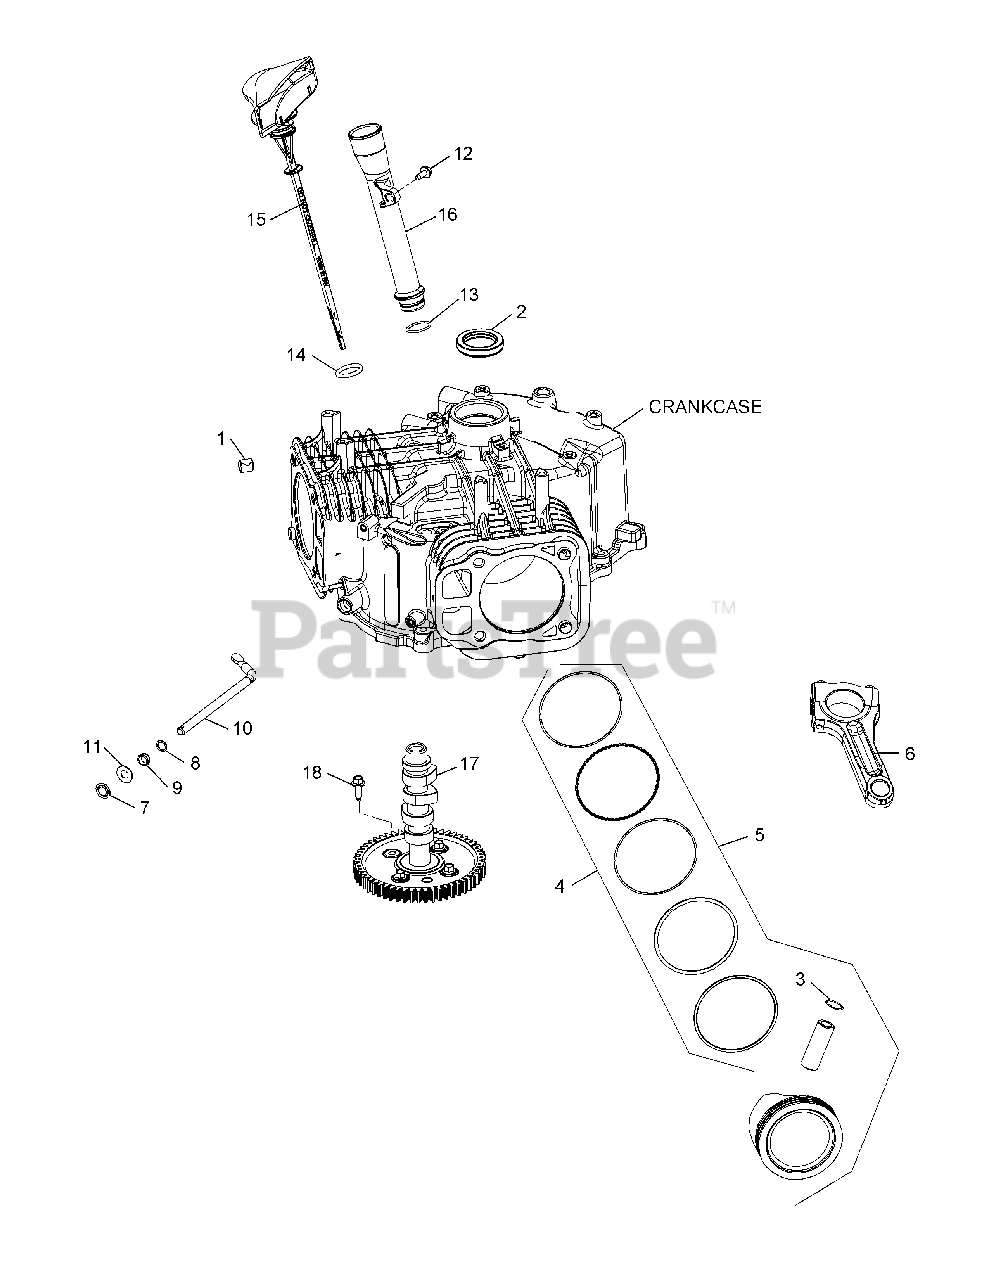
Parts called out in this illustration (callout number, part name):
3	Piston Pin Retainer
4	Piston Ring Set (STD)
4	Piston Ring Set (.08)
4	Piston Ring Set (.25)
4	Piston Ring Set (.50)
5	Piston Kit w/ Ring (STD) (Inc. 9 & 10)
5	Piston Kit w/ Ring (.08)
5	Piston Kit w/ Ring (.25)
5	Piston Kit w/ Ring (.50)
6	Connecting Rod Assembly (STD)
6	Connecting Rod Assembly (.010") (25mm)
7	Ring Retainer
8	Flat Washer, 11/32"
9	Governor Cross Shaft Seal
10	Governor Cross Shaft
11	Flat Washer, 9 mm
12	Thread Forming Screw
13	O-Ring
15	Dipstick Assembly
16	Oil Fill Assembly Tube
17	Camshaft Assembly
18	Hex Flange Screw
